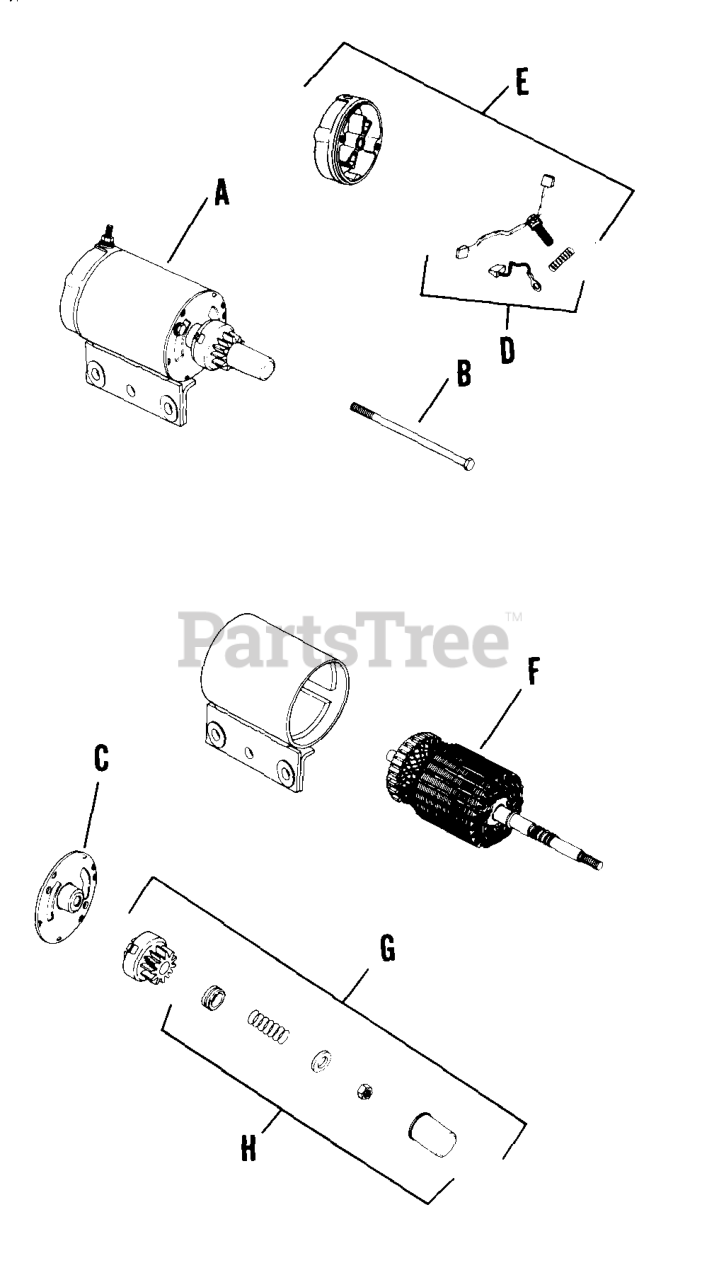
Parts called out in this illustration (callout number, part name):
A	STARTER - USE 45 098 07
C	CAP - USE 45 081 05
D	KIT - USE 52 755 15
E	CAP - DISCONTINUED
